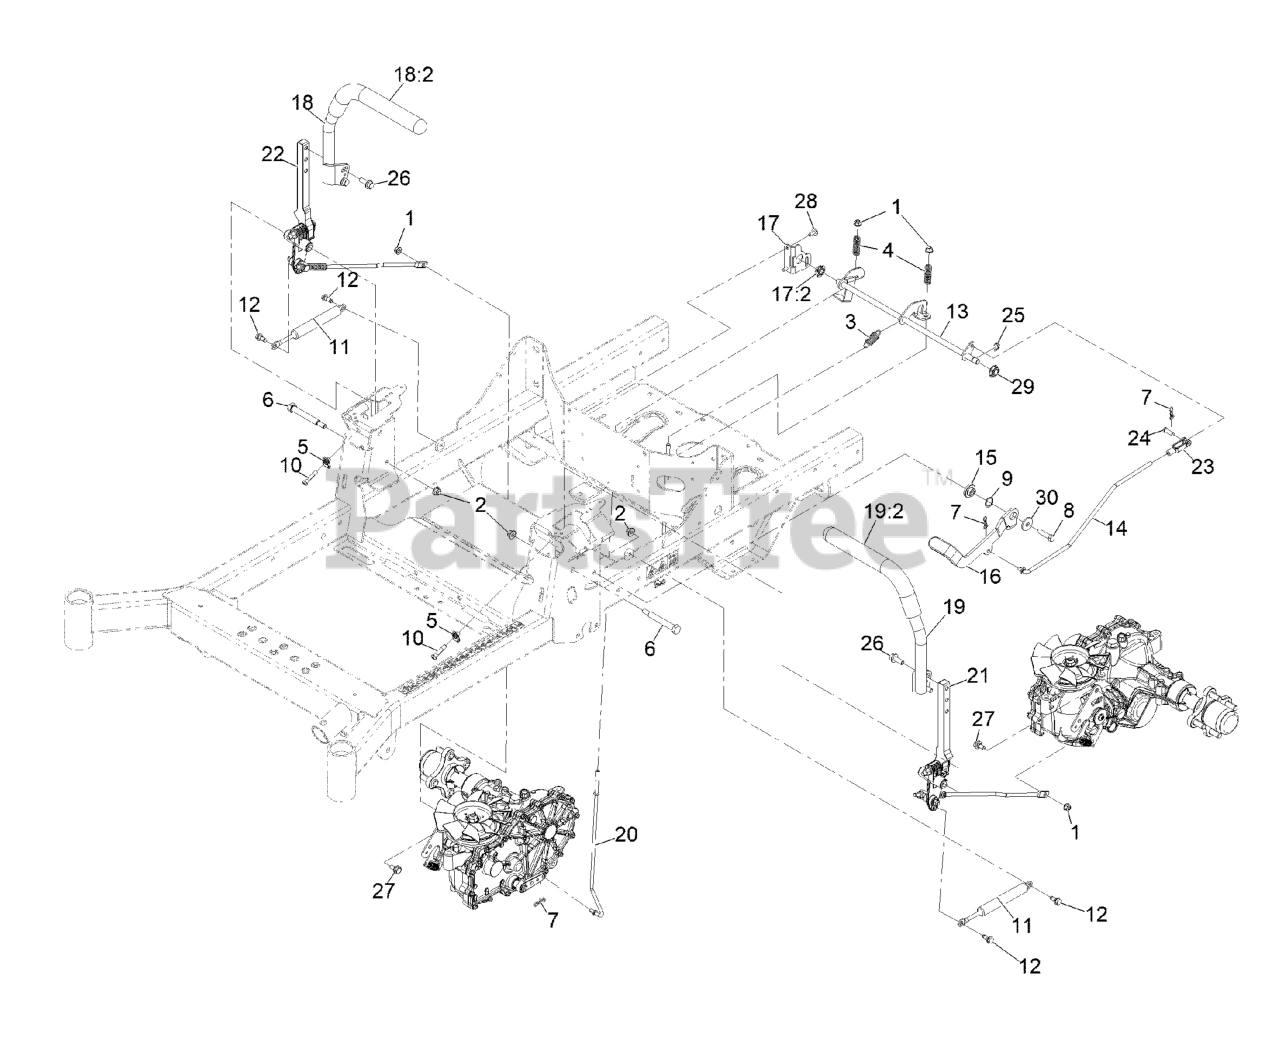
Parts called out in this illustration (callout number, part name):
1	NUT-HF, NI
2	NUT-HF, NI
3	SPRING-EXTENSION
4	SPRING-COMPRESSION
6	BOLT-PIVOT
7	PIN-COTTER, LOCKING
8	SCREW-HH
9	WASHER-WAVE
10	SCREW-HSBH
12	SCREW-SHOULDER
13	SHAFT-BRAKE
14	LINKAGE-BRAKE, UPPER
15	PIVOT-FLANGE
16	LEVER-BRAKE (WITH GRIP)
17	BRACKET-BRAKE
17:2	BEARING-SPHERICAL
18	ASM, MOTION CONTROL W/ GRIP, RT
19	ASM, MOTION CONTROL W/ GRIP, LT
20	LINKAGE-BRAKE, LOWER
21	ASM, MOTION CONTROL LT
22	ASM, MOTION CONTROL RT
23	YOKE-ADJUSTABLE
24	PIN-CLEVIS
25	RING-RETAINING, EXTERNAL
26	SCREW-HHF
27	BOLT-SHOULDER,HFH
28	SCREW-TORX
29	BEARING-SPHERICAL
30	WASHER
